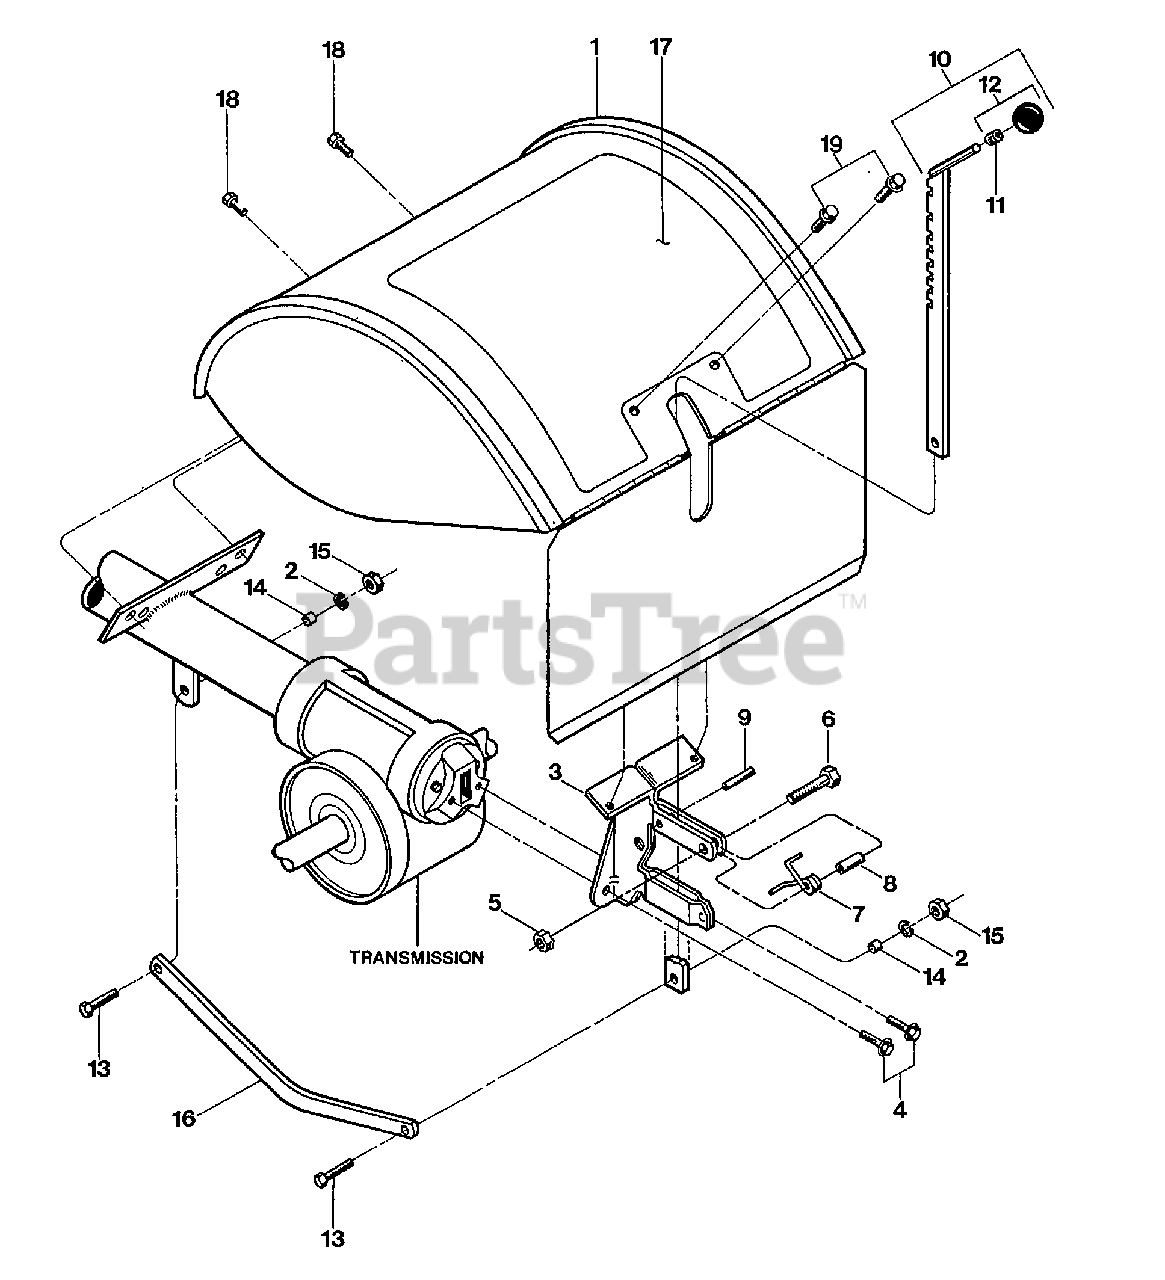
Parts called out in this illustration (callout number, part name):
1	HOOD W/DECAL ECONO OPC (INCL. #17)
2	WASHER-LK .375 @ DEPL
3	BRKT W/ROLL PIN (9308)(INCL. #9)
4	SCR-HFLK 5/16-18X.62 G5ZP
5	NUT-LK 1/4-20
6	SCR-HH 1/4-20X1.0
7	SPRING-TORSION
8	SPACER-.250X.343X.375
9	PIN-ROLL .25 X 1
10	DEPTH REGULATOR W/KNOB (INCL. #11 & 12)
11	RING-TOLERANCE .5325 ID
12	KNOB-CONTROL (INCL. #11)
13	SCR-HH 3/8-16X1.25
14	BUSHING-.5X.375X.3
15	NUT-HEX 3/8-16 ZP
16	DRAG BAR-BENT
17	DECAL-HOOD OPER INST
18	SCR-HWH 5/16-18 X .5 STH
19	SCR-HWH 1/4-20 X .5 STH
